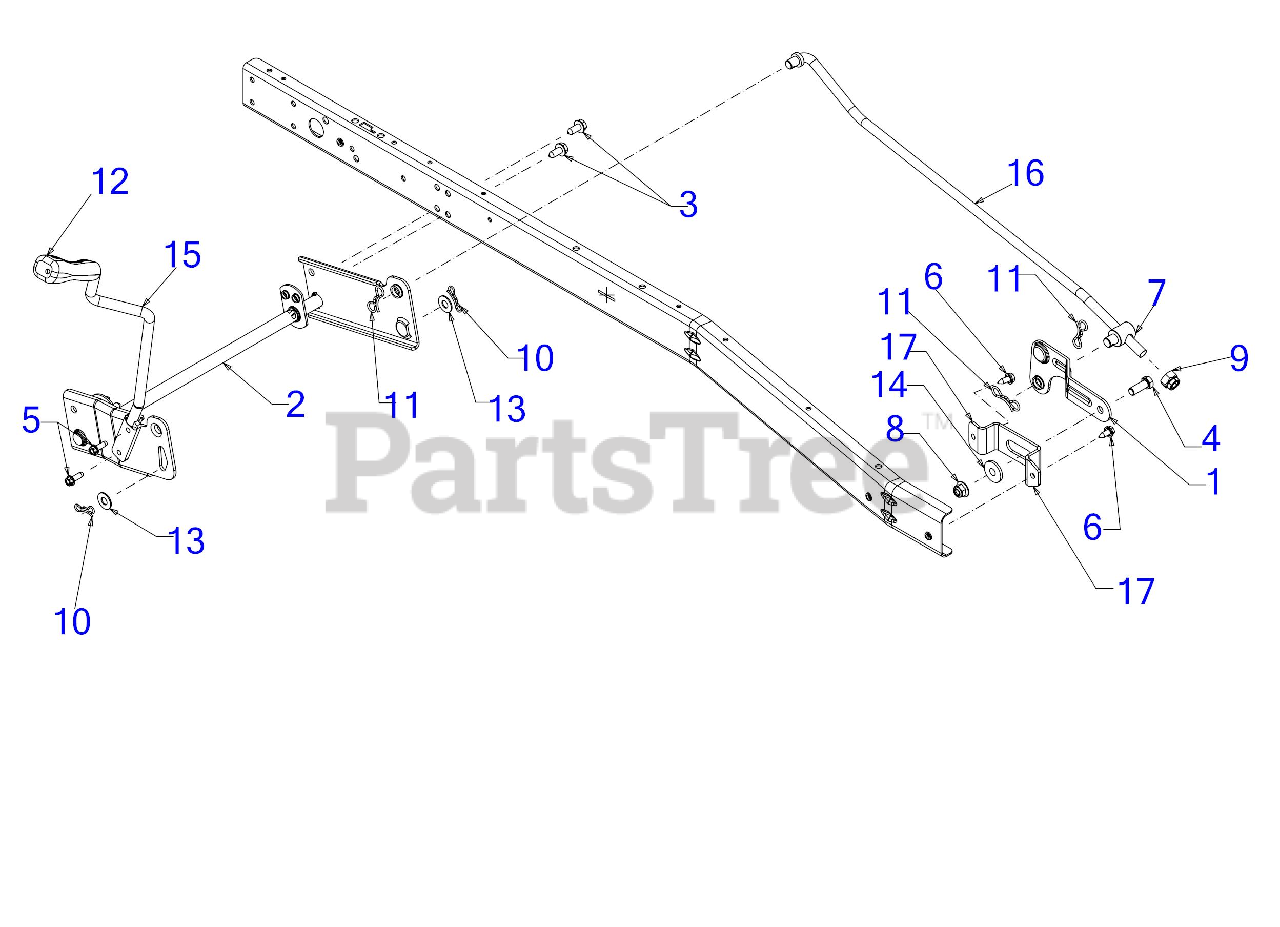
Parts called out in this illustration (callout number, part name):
1	FRONT BRACKET ASSEMBLY
2	LIFT SHAFT ASSEMBLY
3	SCREW 5/16-18 x .750
4	SCREW 3/8-16 x 1 GR5
5	SCREW 1/4-20 x .750
6	SCREW 1/4-20X.625
7	FERRULE
10	BOW TIE COTTER PIN 1/4-5/16
11	PIN:COTTER
12	HANDLE GRIP
13	FLAT WASHER
14	SHOULDER SPACER
15	DECK LIFT ROD
16	DECK LINK ROD
17	DECK HANGER BRACKET (LH)
